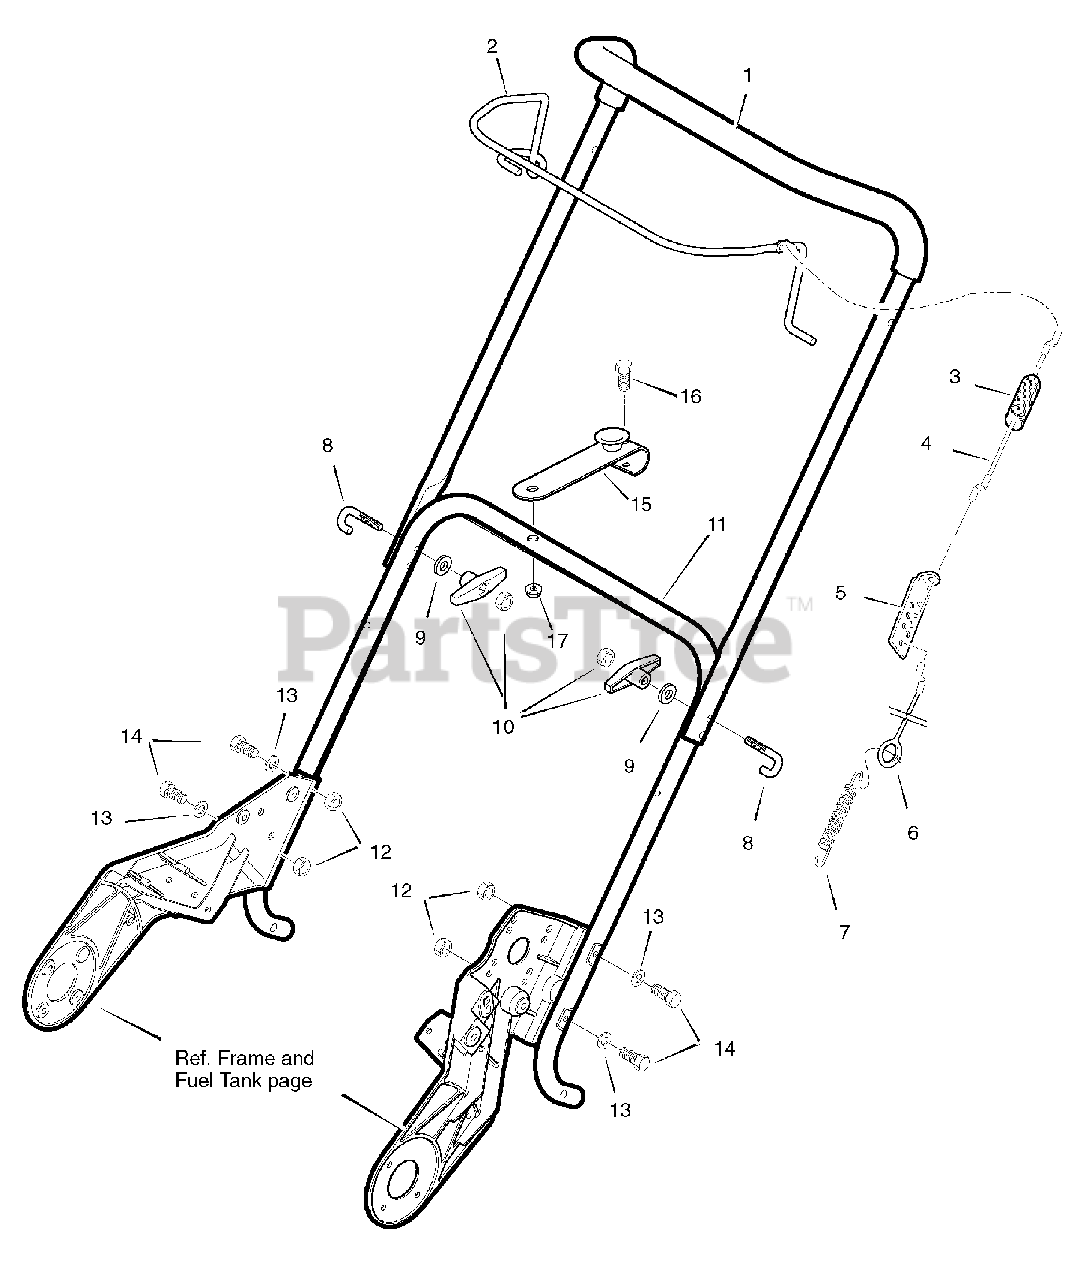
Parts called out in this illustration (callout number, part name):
1	HANDLE & GRIP ASSEMBLY
2	CONTROL, Bail
3	BOOT, Clutch Spring
4	CABLE, Upper Control
5	BRACKET, Control Adjust
6	CABLE, Lower Control
7	SPRING, Extension 3/4 O.D. x .069
9	WASHER, Form 11/32 I.D. 1.0
10	T-KNOB, 3.00 Plastic Black
11	HANDLE, Lower
12	NUT 1/4-20 Hex Control Lock
13	Washer, 9/32 x 5/8 x .065
14	SCREW, 1/4-20 x 1.25
15	BRACKET, Chute Handle Assembly
16	BOLT, Hex Head 1/4-20 x 1.50
17	NUT, 1/4-20 Hex Head Nylock
